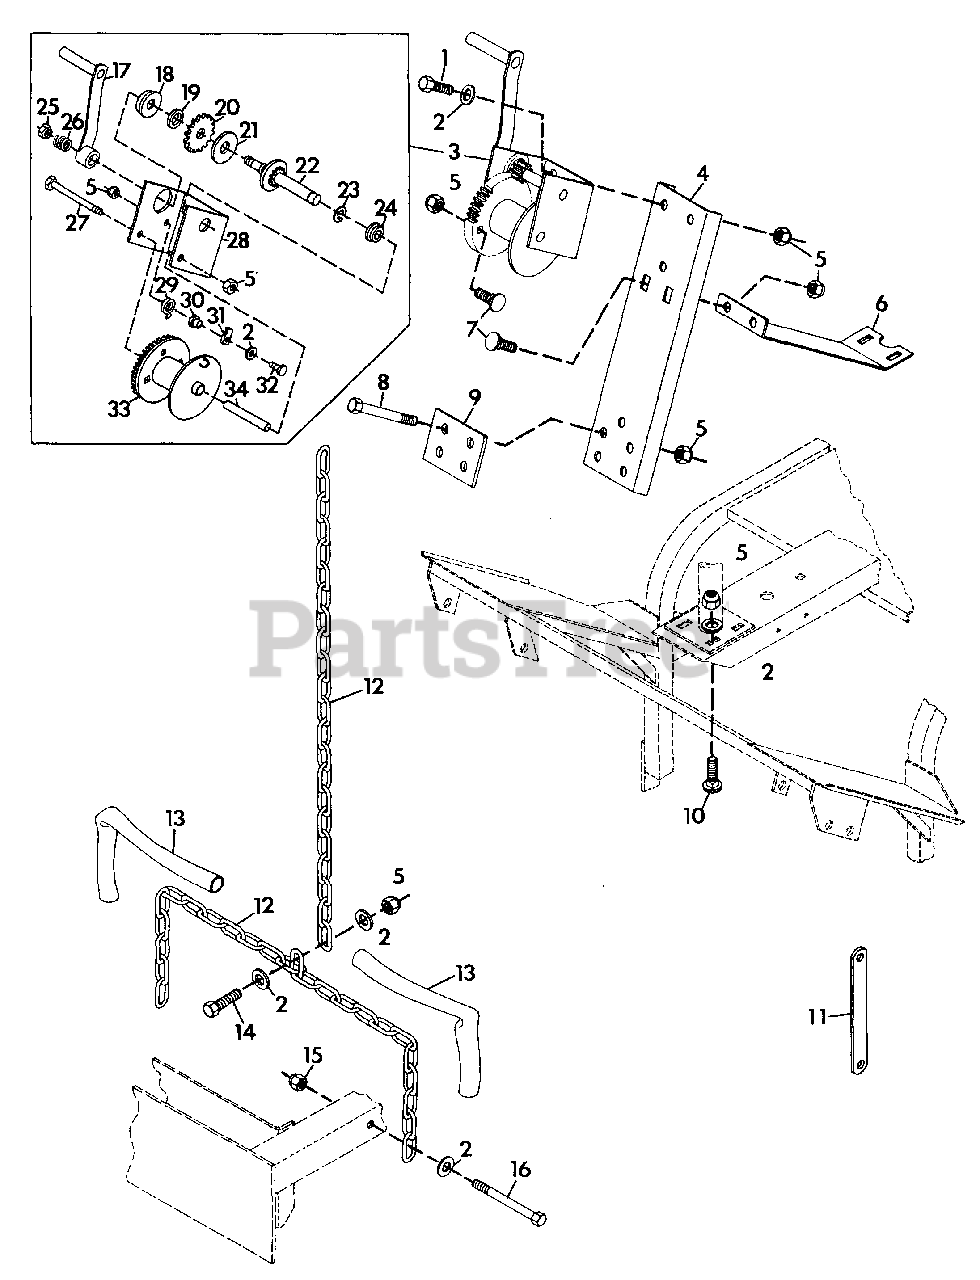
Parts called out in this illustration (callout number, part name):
1	BOLT, HEX 3/8-16X1
2	WASHER, FLAT .406X.812X.065
3	WINCH
4	CHANNEL, WINCH LIFT
5	NUT, LOCK 3/8-16
6	BRACE, WINCH CHANNEL
7	BOLT, 3/8-16X.875 RD HD SQ NK
8	BOLT, HEX 3/8-16X2.5
9	PLATE, CHANNEL CLAMP
10	BOLT, 3/8-16X1.25 RD HD SQ NK
11	BAR, DECK LIFT
12	CHAIN, MOWER LIFT
13	TUBING
14	BOLT, HEX 3/8-16X1.125
15	NUT, LOCK 5/16-24
16	BOLT, HEX 5/16-24X2.75
17	HANDLE, WINCH
18	BUSHING, SHAFT
19	WASHER, PRESSURE
20	WHEEL, RATCHET
21	PLATE, PRESSURE
22	SHAFT, DRIVE
23	E-RING, .625 SHAFT
24	BUSHING, SHAFT
25	NUT, HANDLE
26	SPRING, HANDLE
27	BOLT, HEX 3/8-16X4.50
28	BASE, WINCH
29	SPRING, RATCHET
30	SPACER, RATCHET
31	PAWL, RATCHET
32	BOLT, RATCHET
33	REEL, WINCH
34	SPACER, TUBING
